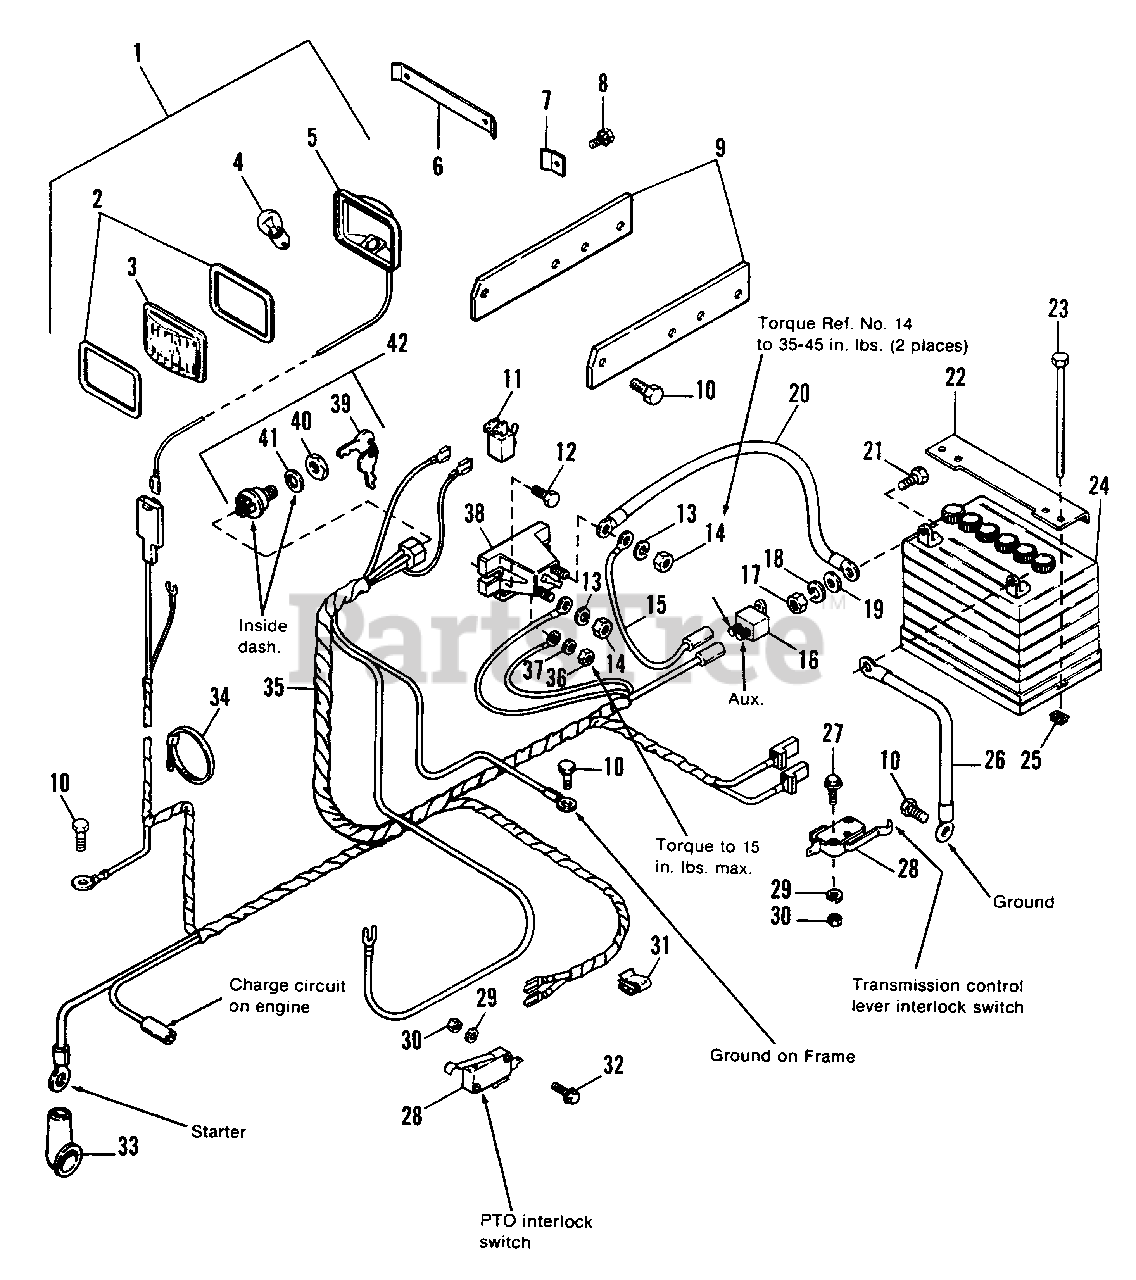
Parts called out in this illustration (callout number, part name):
1	LIGHT ASSY. (Incl. Ref. No. 2, 3, 4 & 5)
3	LENS, Plastic, Clear
5	REFLECTOR ASSY.
6	CLIP, Headlight Center
7	CLIP, Headlight, Side
8	SCREW, Plastite #10-14 x 1-1/2
9	BRACE, Shift Panel
10	SCREW, Taptite, 1/4-20 x 3/8
11	SWITCH ASSY.
12	SCREW, Taptite, 1/4-20 x 5/8
13	LOCKWASHER, 5/16
14	NUT, Hex, 5/16-18
16	CIRCUIT BREAKER
17	NUT, Hex, 1/4-20
18	LOCKWASHER, 1/4
19	WASHER, 1/4
21	CAPSCREW, Hex, 1/4-20 x 3/4
22	CLAMP, Battery
23	CAPSCREW, Hex, 1/4-20 x 7-1/2
24	BATTERY SERVICE KIT, 39 Amp.
25	NUT, Retainer, 1/4-20
27	SCREW, Rd. Hd., Phil. #5-40 x 3/4
28	SWITCH, Interlock
29	LOCKWASHER, #5
30	NUT, Hex, 5-40
31	CLIP, Speed
32	SCREW, Taptitie, 5-40 x 3/4
33	COVER, Terminal
34	TIE, Selflocking
35	HARNESS, Wiring
36	NUT, Hex, 10-32
37	LOCKWASHER, 10
38	SOLENOID
39	KEYS, Set of 2
40	NUT, 5/8-32
41	LOCKWASHER. Int. Tooth, 5/8
42	SWITCH, Ignition (Incl. Ref. No. 39, 40 & 41)
